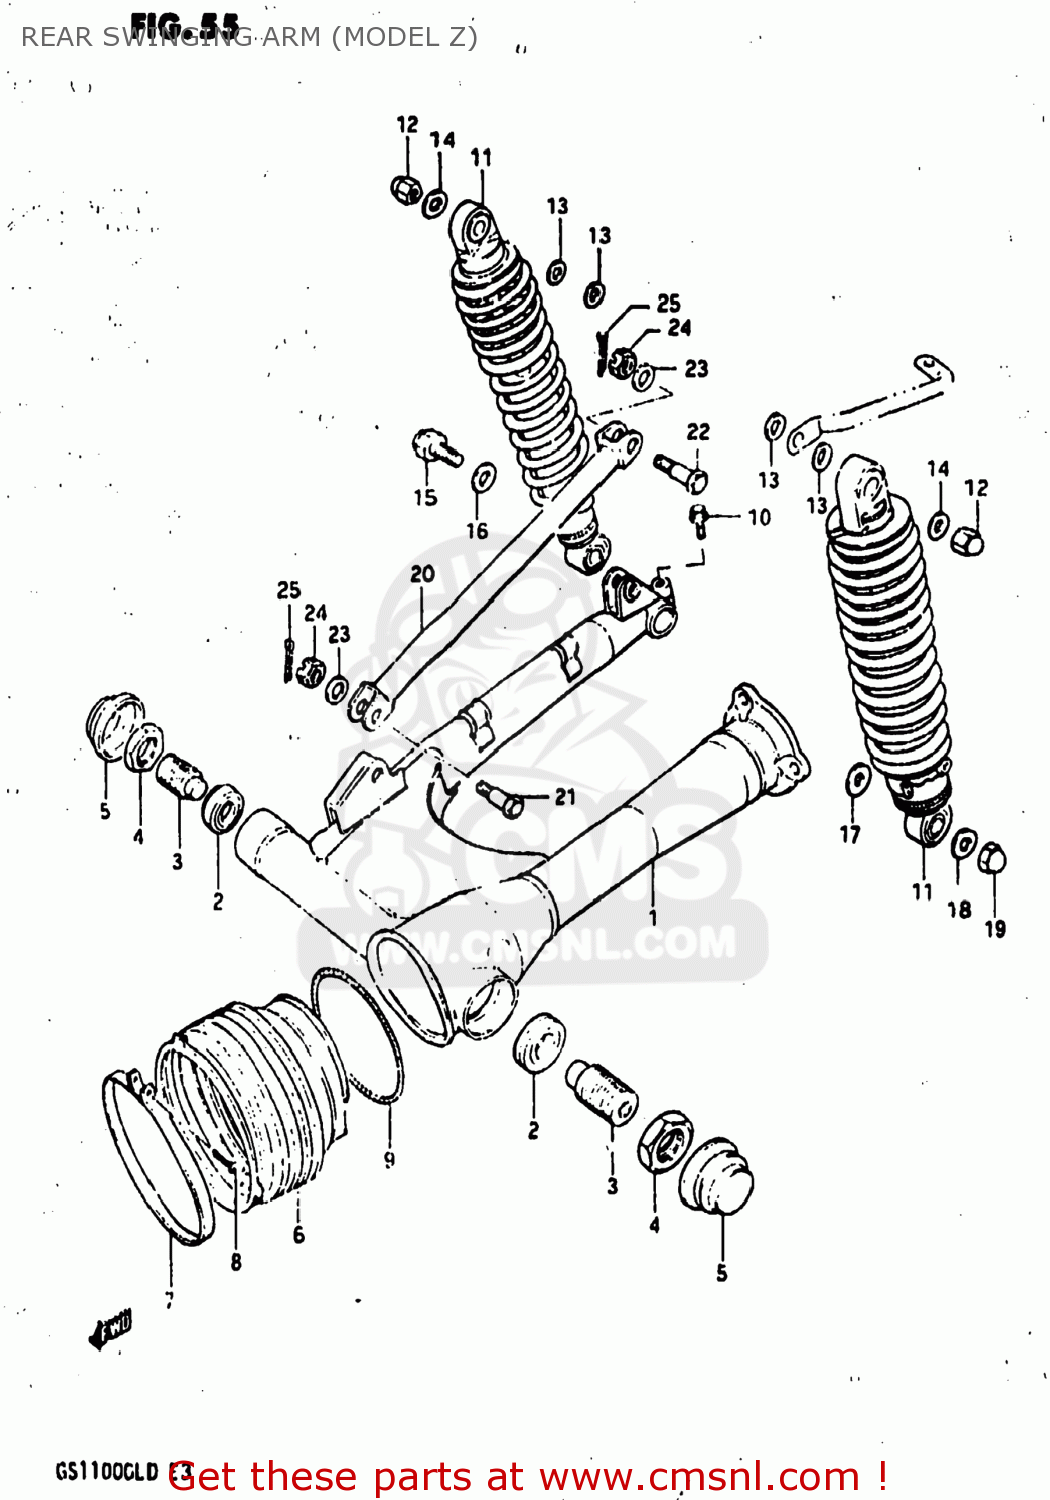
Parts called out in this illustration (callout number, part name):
1	SWING ARM SET,REAR (B
2	BEARING(17X40X13.25)
3	BOLT,REAR SWING ARM PIVOT
4	NUT
5	CAP,REAR SWING ARM PIVOT
6	BOOT,PROPELLER SHAFT
7	CLAMP
8	SCREW 4X25
9	SPRING,PROPELLER SHAFT
10	BOLT
11	ABSORBER ASSEMBLY,REAR SHOCK
12	NUT
13	WASHER
14	WASHER
15	BOLT 12X33
16	WASHER (12.5X24X1.6)
17	WASHER
18	WASHER
19	NUT, LOWER LH
20	TORQUE LINK,REAR
21	BOLT
22	BOLT(10X39)
23	WASHER
24	NUT
25	PIN 20X20
